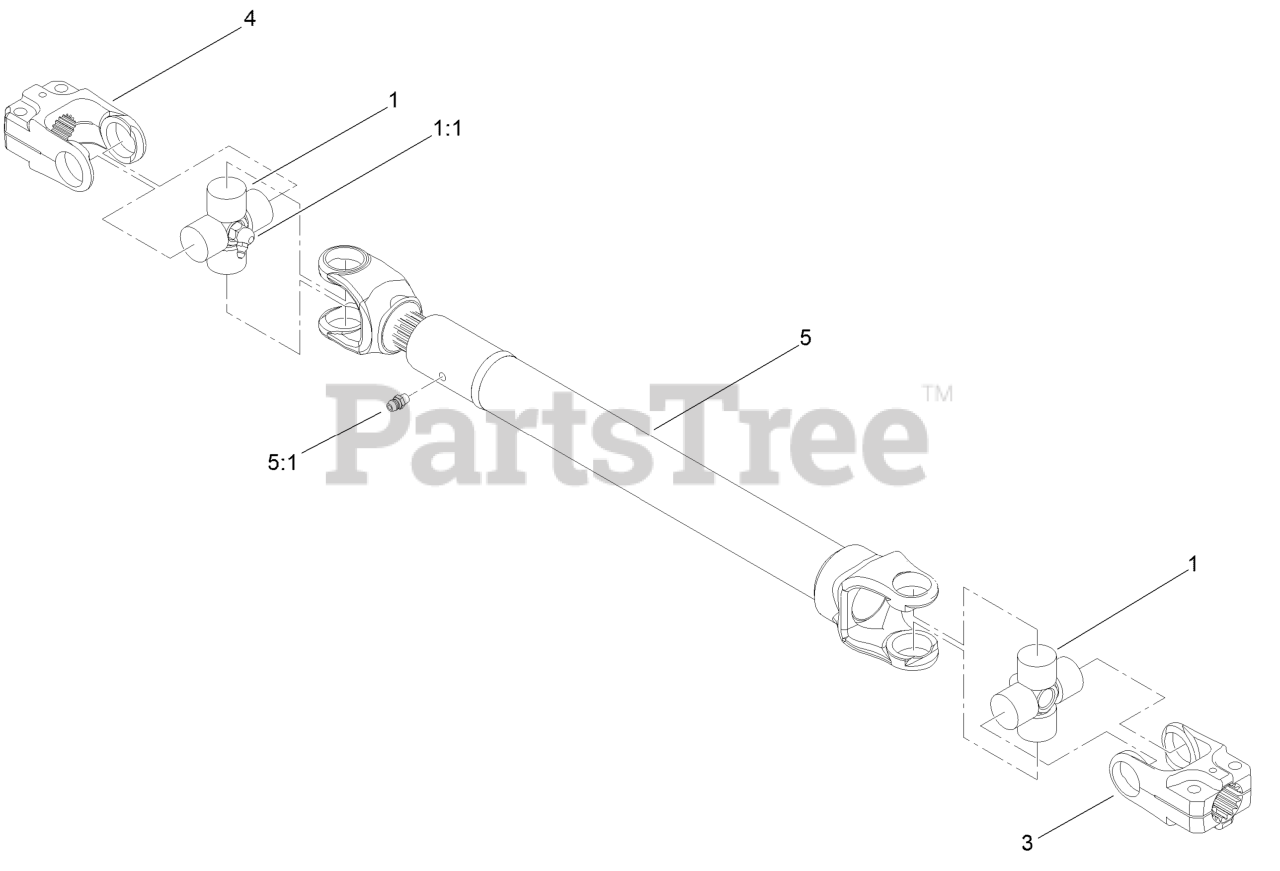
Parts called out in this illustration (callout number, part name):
1	Cross And Bearing Kit
1:1	Fitting-Grease
3	Yoke-End
4	Yoke-End
5	Tube-Yoke, Slip
5:1	Fitting-Grease
